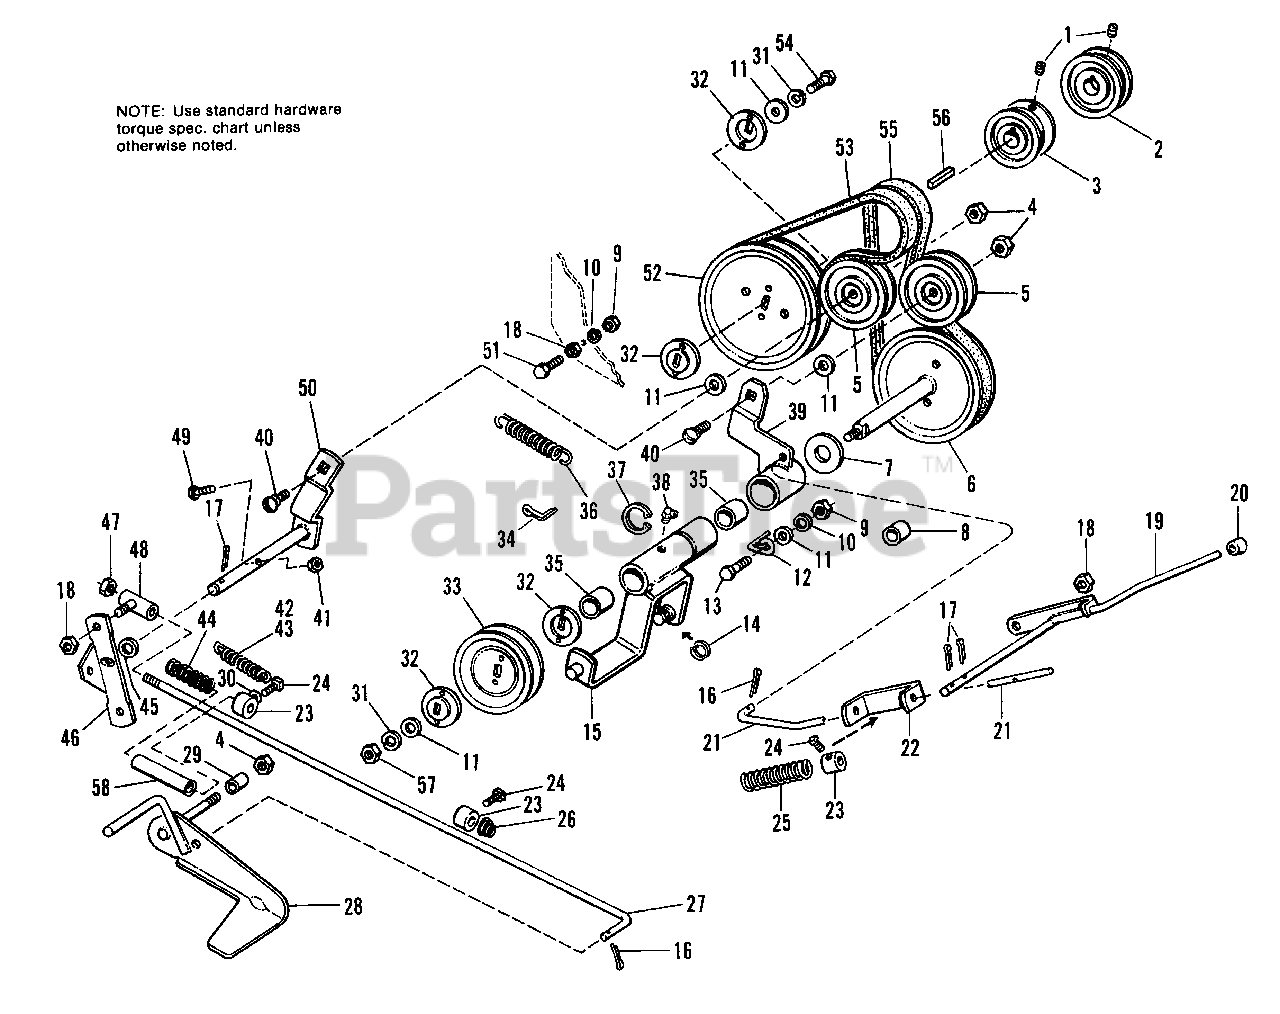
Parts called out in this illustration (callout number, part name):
1	SETSCREW, 5/16-18 x 5/16
2	PULLEY, Engine
3	PULLEY, Drive
4	LOCKNUT, Hex, 3/8-16
5	PULLEY, Idler
6	PULLEY & SHAFT ASSY
9	NUT, Hex, Full, 5/16-18 (Qty. 1 on 990774, 990775)
10	LOCKWASHER, 5/16 (Qty. 1 on 990774, 990775)
11	WASHER, Plain, 5/16 (Qty. 1 on 990774, 990775)
12	STOP, Belt
13	CAPSCREW, Hex Hd, 5/16-18 x 7/8
14	RING, Retaining
15	HOUSING ASSY
16	PIN, Cotter, 3/32 x 3/4
17	PIN, Cotter, 1/8 x 1
18	LOCKNUT, Hex, 5/16-18
19	HANDLE ASSY, P.T.O. Control
21	ROD, Clutch
22	GUIDE ASSY, Rod
23	COLLAR, Set
24	SETSCREW, 1/4-20 x 3/8
26	SPRING, Conical
27	ROD, Clutch
28	PEDAL ASSY, Foot
30	WASHER, Plain, 3/16
31	LOCKWASHER, 3/8
32	WASHER, Special
33	PULLEY Mower Drive
34	PIN, Cotter
35	BEARING, Needle
37	RING, Retaining
38	FITTING, Grease
39	LEVER ASSY, Idler
40	BOLT, Carriage, 3/8-16 x 1
41	LOCKNUT, Hex, 1/4-20
42	SPRING
43	SPRING
44	SPRING, Compression
45	WASHER, Plain, 7/16
47	NUT, Elastic Stop, 5/16-18
48	GUIDE ASSY, Rod
49	CAPSCREW, Hex Hd, 1/4-20 x 1
50	ARM ASSY, Idler Pulley
51	CAPSCREW, Hex Hd, 5/16-18 x 1-1/2
52	PULLEY, Transmission
54	CAPSCREW, Hex Hd, 5/16-18 x 7/8
56	KEY
57	NUT, Hex, Full, 3/8-16
58	SPACER
